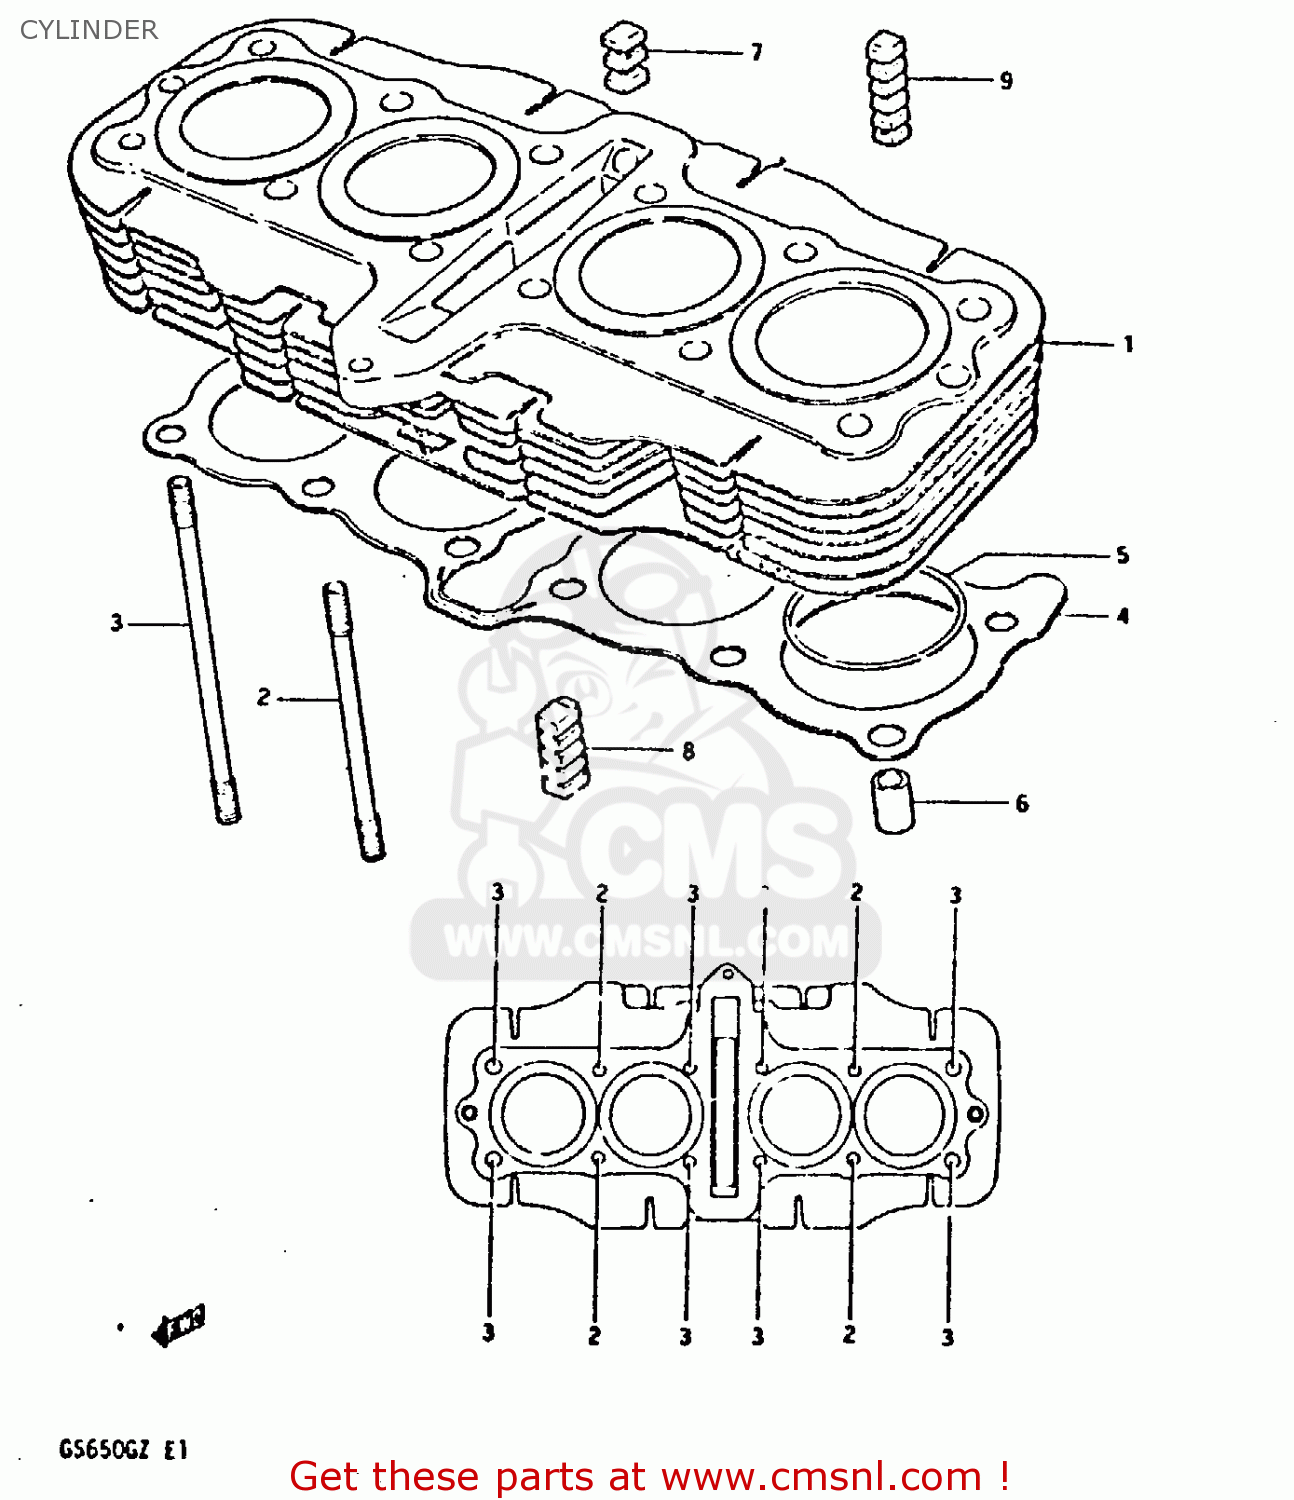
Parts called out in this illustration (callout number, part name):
1	CYLINDER
2	BOLT,STUD
3	BOLT,STUD
4	GASKET,CYLINDER (MCA)
5	O RING(D:2,ID:61)
6	PIN
7	PAD,CYLINDER
8	PAD,CYLINDER
9	PIN,EXHAUST VALVE
